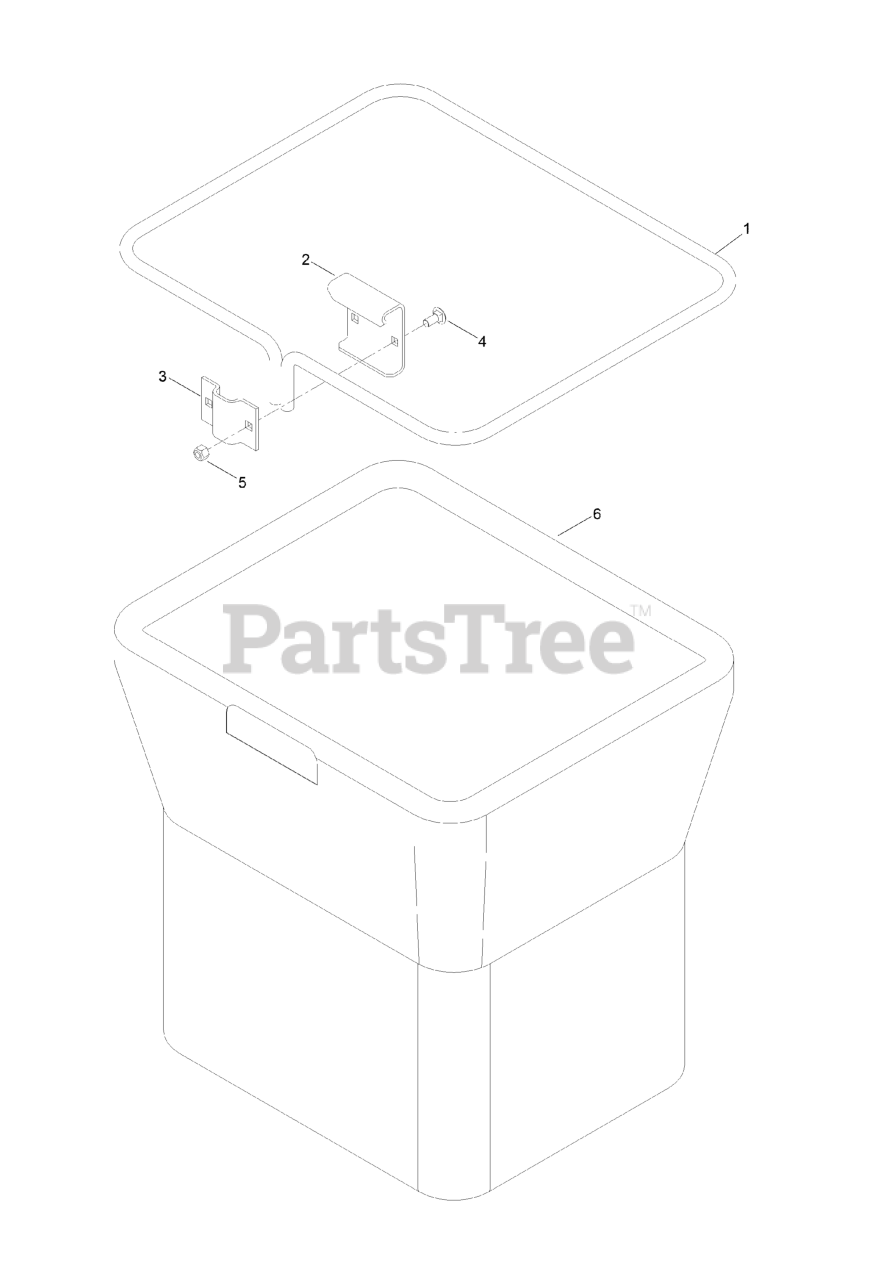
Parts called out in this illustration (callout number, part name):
1	FRAME-BAG
2	HANGER-BAG
4	BOLT-CARR
5	NUT-LOCK, NI
6	BAG
